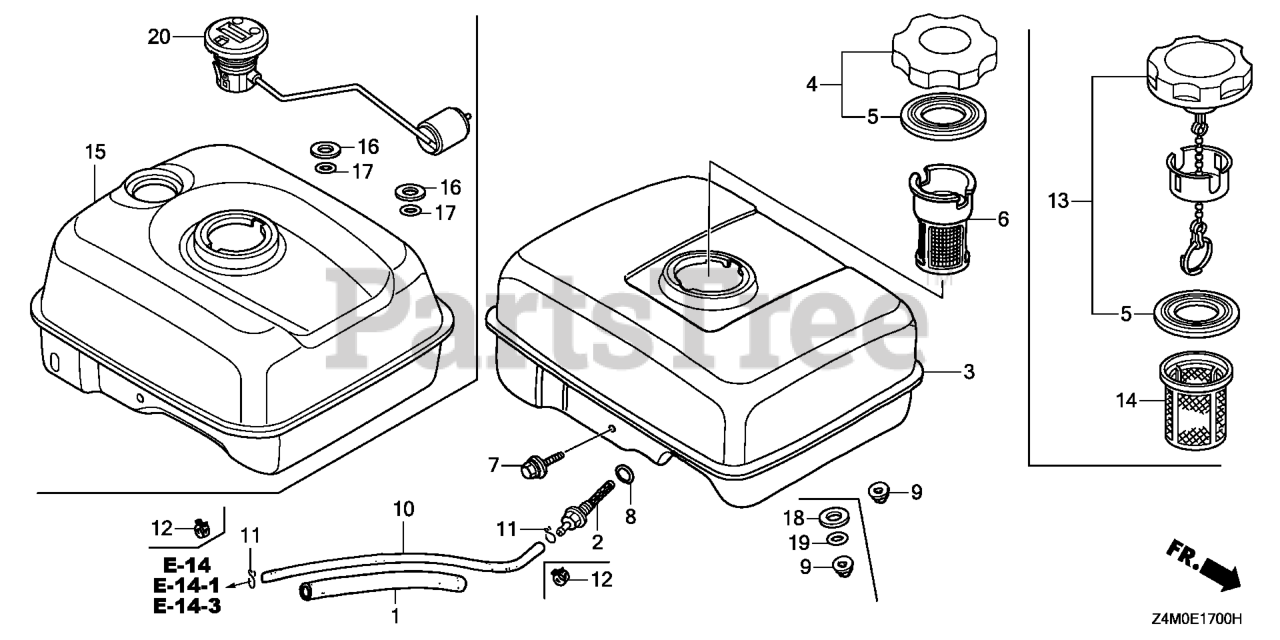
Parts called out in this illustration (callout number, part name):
1	RUBBER, SUPPORTER (107MM)
2	JOINT, FUEL TANK
5	GASKET, FUEL FILLER CAP
5	GASKET, FUEL FILLER CAP (39X62X3) (TOUYOUSYA)
7	BOLT, FLANGE (6X29)
8	O-RING (14MM) (ARAI) Use up to Engine SN 2949254.
9	NUT, FLANGE (6MM)
10	TUBE, FUEL (4.5X145) (FKM)
12	CLIP, TUBE (D8)
13	CAP, FUEL FILLER
15	TANK, FUEL *NH31* (MCKINLEY WHITE)
15	TANK, FUEL *NH1* (BLACK)
